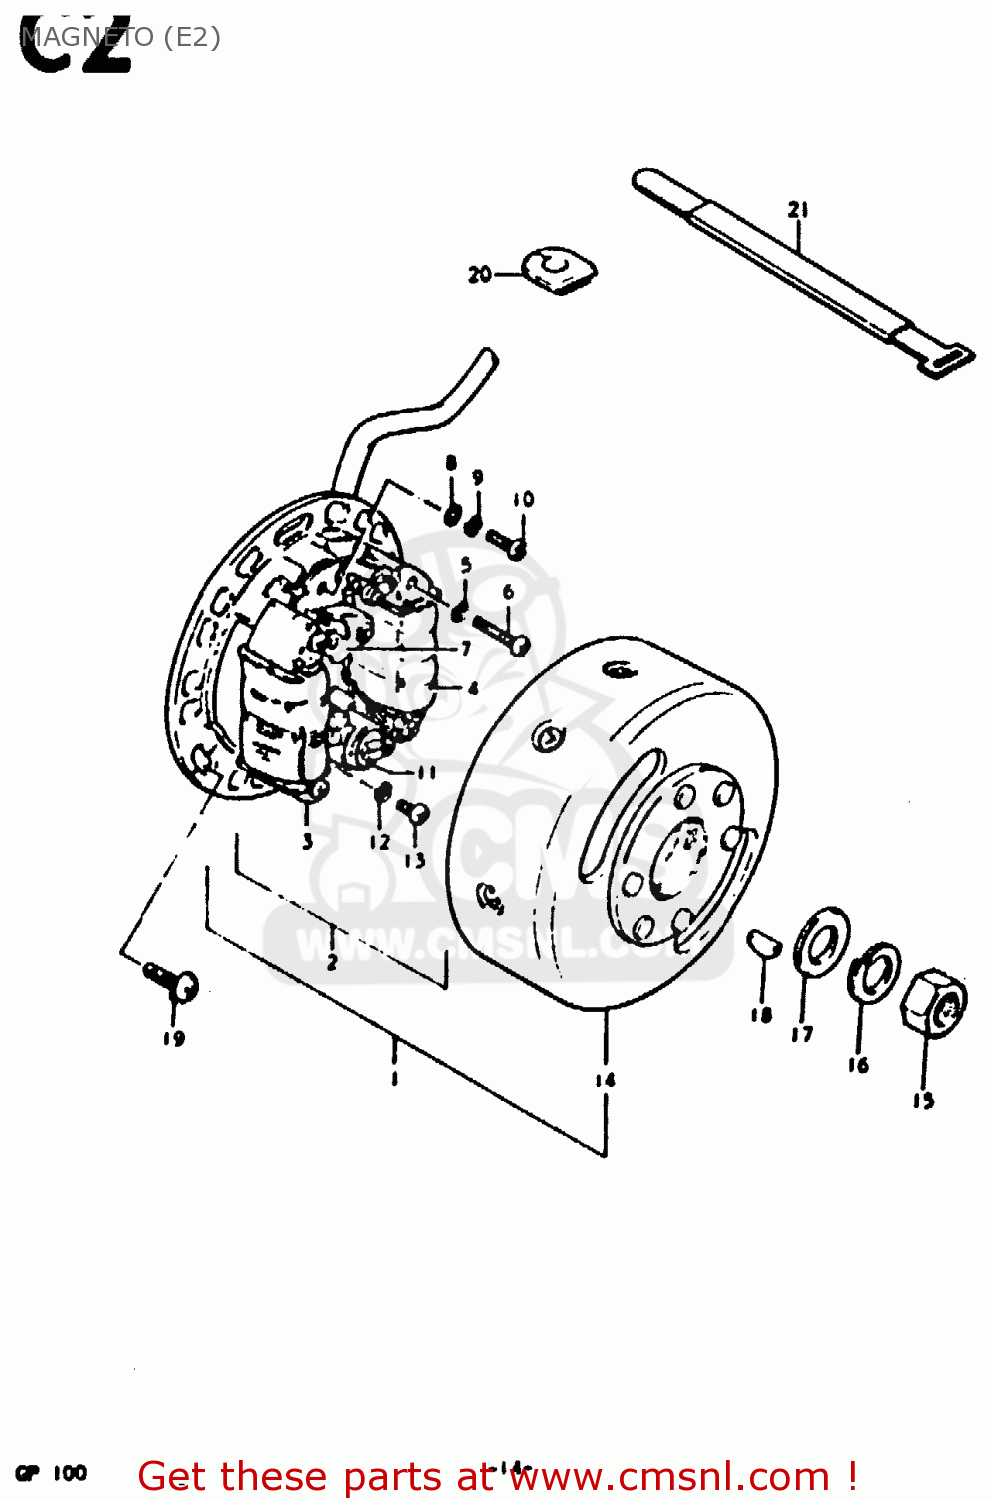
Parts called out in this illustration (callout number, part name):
1	MAGNETO ASSY
2	STATOR ASSY
3	COIL, LIGHTING
4	COIL,PRIMARY
5	LOCK WASHER
6	SCREW 4X25
7	POINT ASSY,CONTACT
8	WASHER
9	LOCK WASHER
10	SCREW(4X10)
11	CONDENSER
12	LOCK WASHER
13	SCREW 4X10
14	ROTOR, FLYWHEEL
15	NUT (10MM)
16	LOCK WASHER
17	WASHER
18	KEY
19	SCREW(5X14)
20	GROMMET
21	CLAMP
